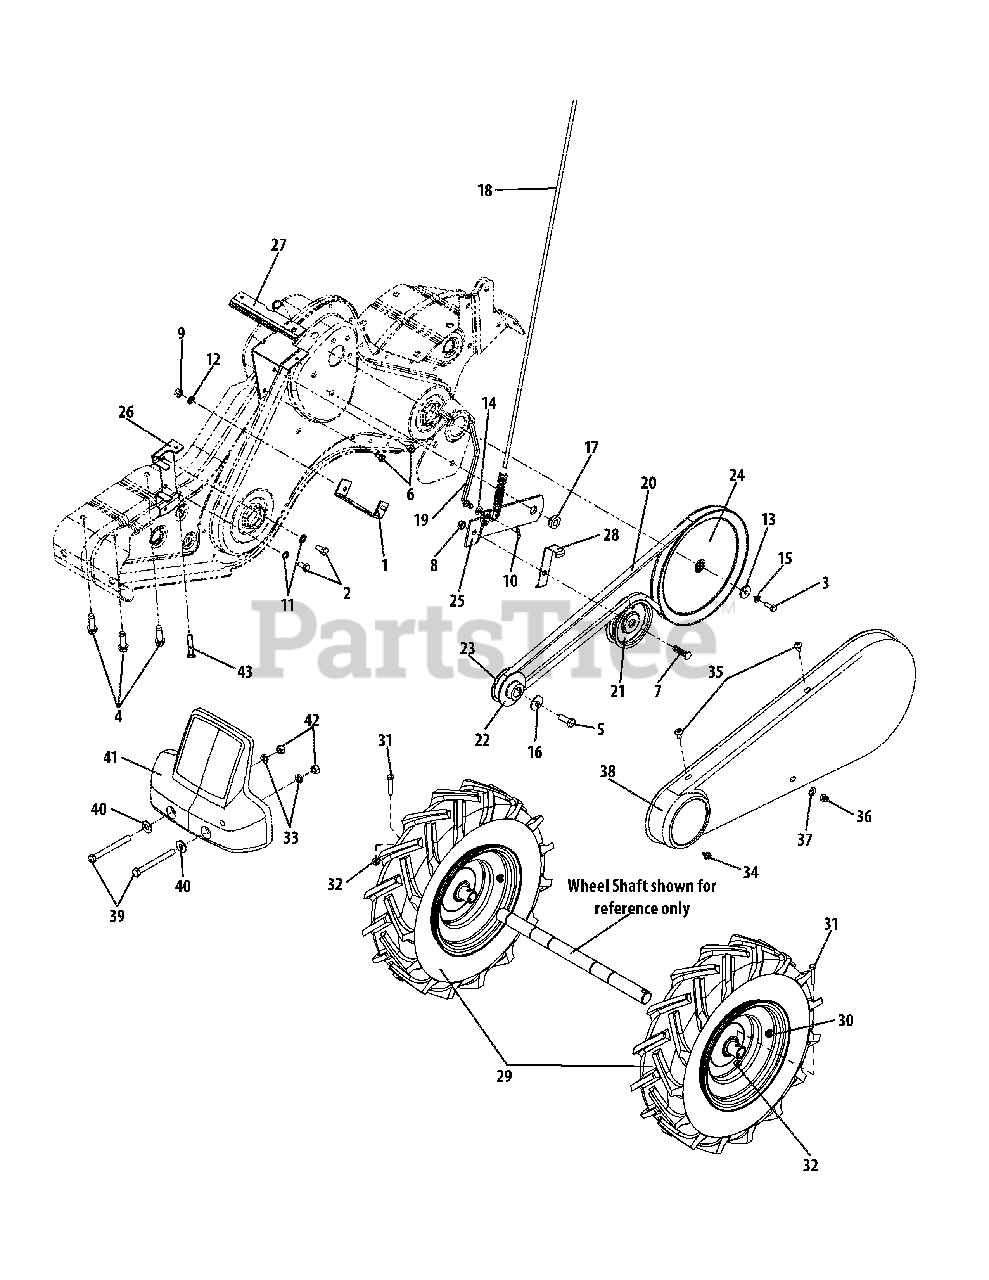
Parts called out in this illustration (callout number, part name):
2	Hex Bolt, 5/16-24 x .62"
3	Hex Bolt, 1/4-28 x .75"
4	Hex Washer Screw, .3/8-16 x 1.25"
5	Hex Bolt, 3/8-24 x 1.0
6	Hex Washer Screw
7	Hex Cap Screw,3/8 -16 x 1.25
8	Lock Jam Nut, 3/8-16
9	Hex Nut, 5/16-18
10	Internal Cotter Pin
11	Hairpin Clip
12	Lock Washer,5/16"
13	Flat Washer, .25 ID x .93 OD
14	Spring Washer, .317 ID x .625 OD
15	Lock Washer 1/4" ID
16	Bell Washer, .396 ID x 1.14 OD
17	Shoulder Nut, 7/16-20
18	Clutch Cable
19	Idler Pulley Rod
20	V-Belt
21	Flat Idler w/Flange, 3.75 OD
22	Outer Engine Pulley Half
23	Inner Engine Pulley Half
24	Input Pulley
25	Idler Bracket
29	Wheel Assembly, 16.0 x 4.6 x 8
30	Air Valve
31	Hex Head Screw, 1/4-20
32	Flange Lock Nut, 1/4-20
33	Lock Washer, 1/2
34	Hex Screw, 1/4-20 x .375
35	Screw, 1/4-14 x .625
36	Lock Nut
37	Flat Washer, .271 ID x .630 OD
39	Hex Head Screw, 1/2-13 x 5.00
40	Flat Washer, 1/2 x 1.25 x .10
41	Counterweight
42	Hex Nut, 1/2-13
